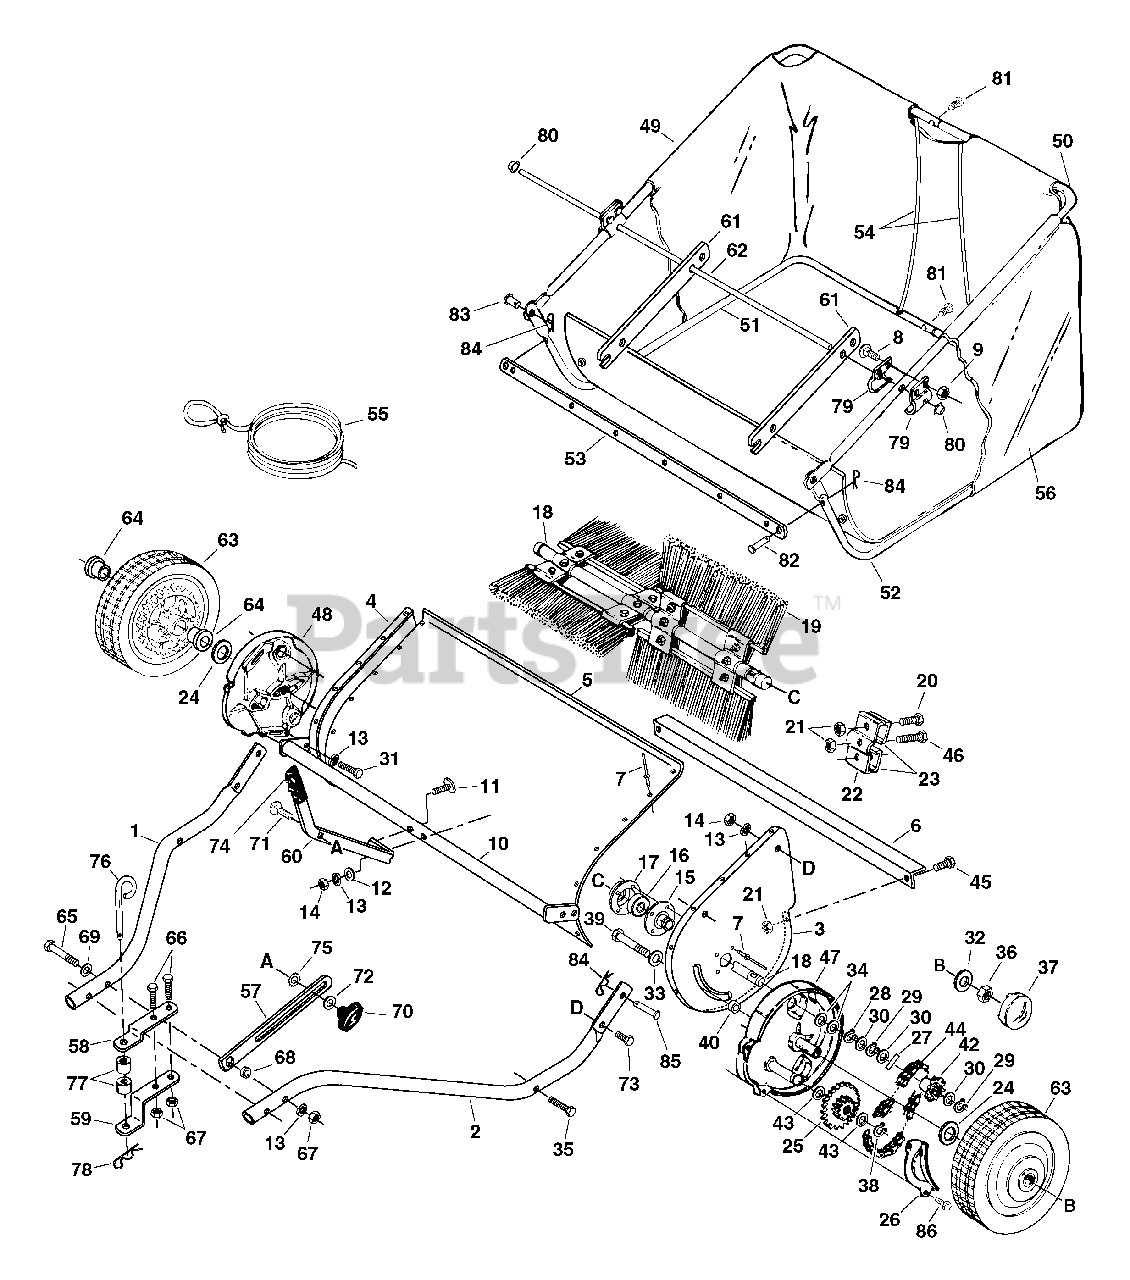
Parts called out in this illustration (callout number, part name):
1	Hitch Tube, R.H.
2	Hitch Tube, L.H.
3	End Plate, L.H.
4	End Plate, R.H.
5	Wrapper
6	Brace, Rear Support
7	Rivet, Pop
8	Bolt, Carriage 5/16-18 x 3/4"
9	Nut, Hex 5/16-18 (SEMS)
10	Height Adjustment Ass'y.
11	Bolt, Cv. Hd. 5/16-18 x 1-5/8" Lg.
12	Washer, Bowed 1" x .32" x .06"
13	Lock Washer, 5/16"
14	Nut, Hex 5/16-18 Thread
15	Brush Bushing Ass'y.
16	Ball Bearing
17	Retainer, Dust Cover
18	Brush Shaft, 38"
19	Brush, 38"
20	Bolt, Hex 1/4-20 x 3/4" Lg.
21	Nut, Hex Lock 1/4-20 Thread
22	Retainer, Brush (Double)
23	Retainer, Brush (Single)
24	Washer, Flat 1-1/8" x .78" x .025"
25	Sprocket / Gear
26	Dust Cover
27	Dowel Pin (Drive)
28	Ring, Retaining 3/4"
29	Ring, Retaining .594"
30	Washer, Shim 1-1/8" x .594" x .025"
31	Bolt, Hex 5/16-18 x 3/4" Lg.
32	Washer, Flat 1-1/2" x .375" x .062"
33	Washer, 3/8" Std. Wrt.
34	Washer, Flat .78" x 1.25" x .06"
35	Bolt, Hex 5/16-18 x 1-3/4" Lg.
36	Nut, Hex Lock 3/8-24 Thread
38	Ring, Retaining 1/2"
39	Bolt, Hex 3/8-24 x 3-1/2" Lg.
40	Bushing, Spacer
42	Sprocket, Ratchet L.H.
43	Washer, 1/2" x 1" x .02"
44	Chain, Roller
45	Bolt, Hex 1/4-20 x 1/2" Lg.
46	Bolt, Hex 1/4-20 x 1" Lg.
47	Housing, Wheel Drive Ass'y. L.H.
48	Housing, Wheel Drive Ass'y. R.H.
49	Tube, Upper Hopper Frame R.H.
50	Tube, Upper Hopper Frame L.H.
51	Tube, Lower Hopper Frame R.H.
52	Tube, Lower Hopper Frame L.H.
53	Strap, Bag Frame
54	Rod, Hopper Support
55	Hopper Rope
56	Hopper Bag, 38"
57	Strap, Height Adjustment
58	Bracket, Hitch
59	Bracket, Hitch
60	Handle, Height Adjustment
61	Bag Arm
62	Rod, Hopper Bag Pivot
63	Wheel & Tire Ass'y. (White)
64	Wheel Bearing
65	Bolt, Hex 5/16-18 x 3" Lg.
66	Bolt, Hex 5/16-18 x 2-1/4" Lg.
67	Nut, Hex Lock 5/16-18 Thread
68	Bushing, Spacer
69	Washer, Flat 11/32" x 11/16"
70	Knob, Wing 5/16-18 Thread
71	Bolt, Carriage 5/16-18 x 3/4" Lg.
72	Washer, Flat 5/16" Std. Wrt.
73	Bolt, Hex 5/16-18 x 1" Lg.
74	Grip, Height Adjust
75	Washer, Tooth Lock 5/16"
76	Pin, Hitch
77	Tube, Hitch Spacer
78	Hairpin Cotter, 1/8" #4
79	Clamp, Hopper Mount
80	Palnut, 3/8"
81	Plug, 1/4"
82	Pin, Clevis 1/4" x 1-1/8" (Special)
83	Pin, Clevis 3/8" x 1/2" (Special)
84	Pin, Hair Cotter 3/32" #3
85	Pin, Clevis 3/8" x 3/4" Lg.
86	Screw, #12 x 1/2" Hex Head
